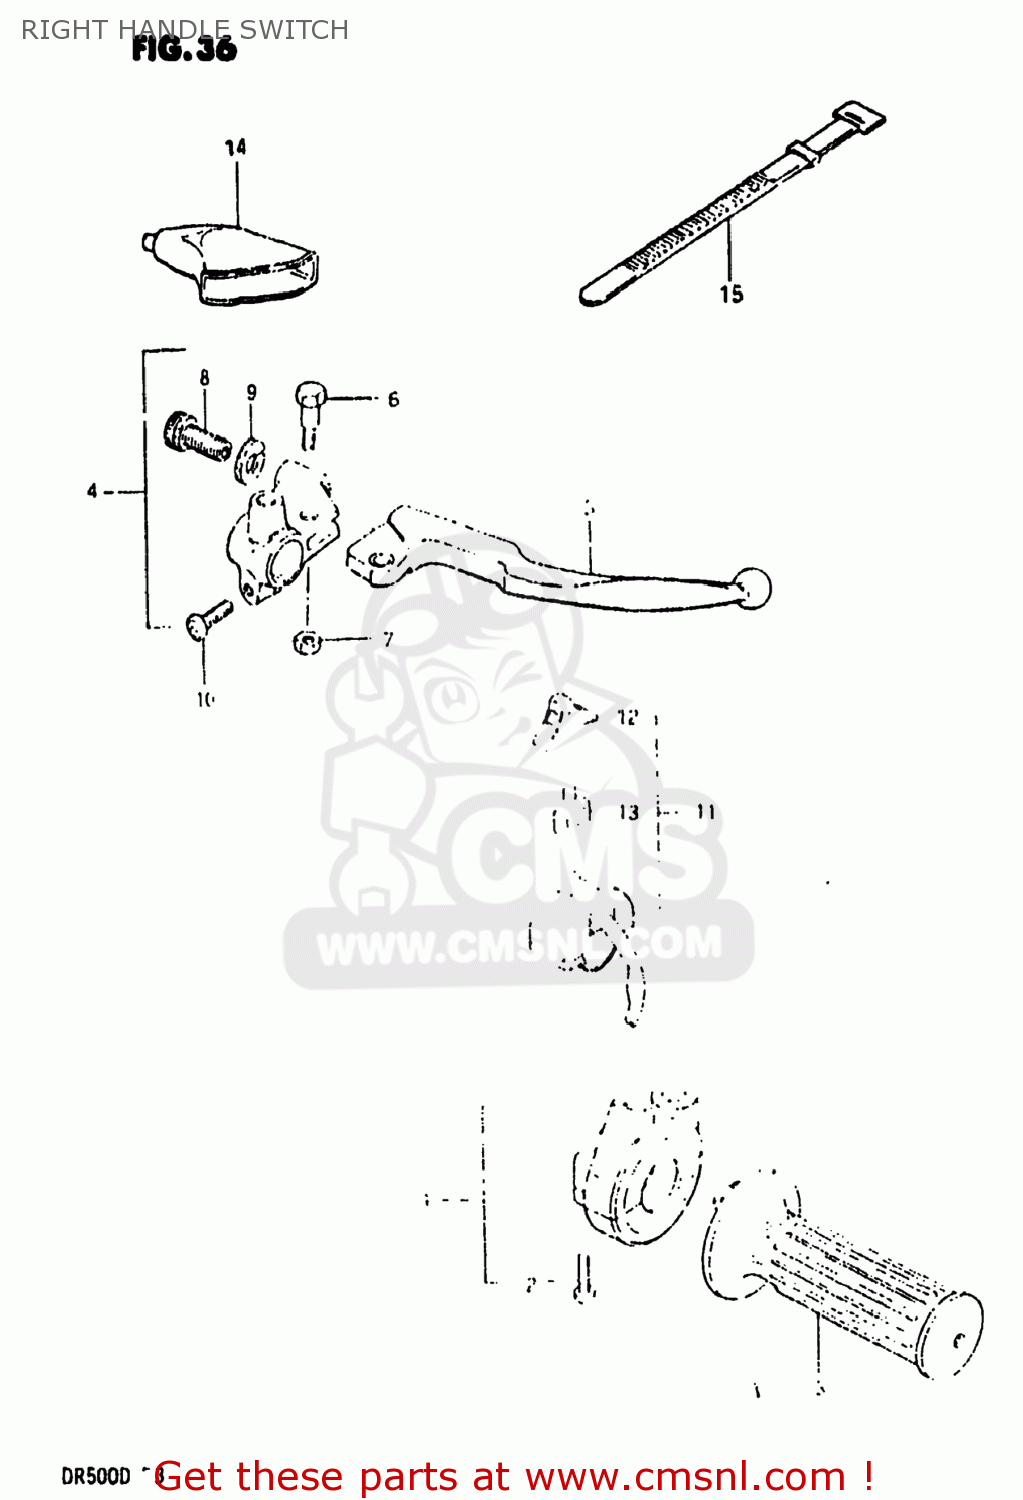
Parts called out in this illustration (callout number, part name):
1	CASE ASSY,THROTTLE
2	SCREW 5X20
3	GRIP,THROTTLE
4	LEVER ASSEMBLY,BRAKE
5	LEVER,BRAKE
6	BOLT,LEVER
7	NUT 6MM
8	ADJUSTER,CABLE
9	NUT,CABLE ADJUSTER
10	SCREW
11	SWITCH ASSY,LIGHTING
12	KNOB,LIGHTING & DIMMER
13	BLOCK,LIGHTING/DIMMER
14	COVER,CLUTCH LEVER
15	CLAMP
